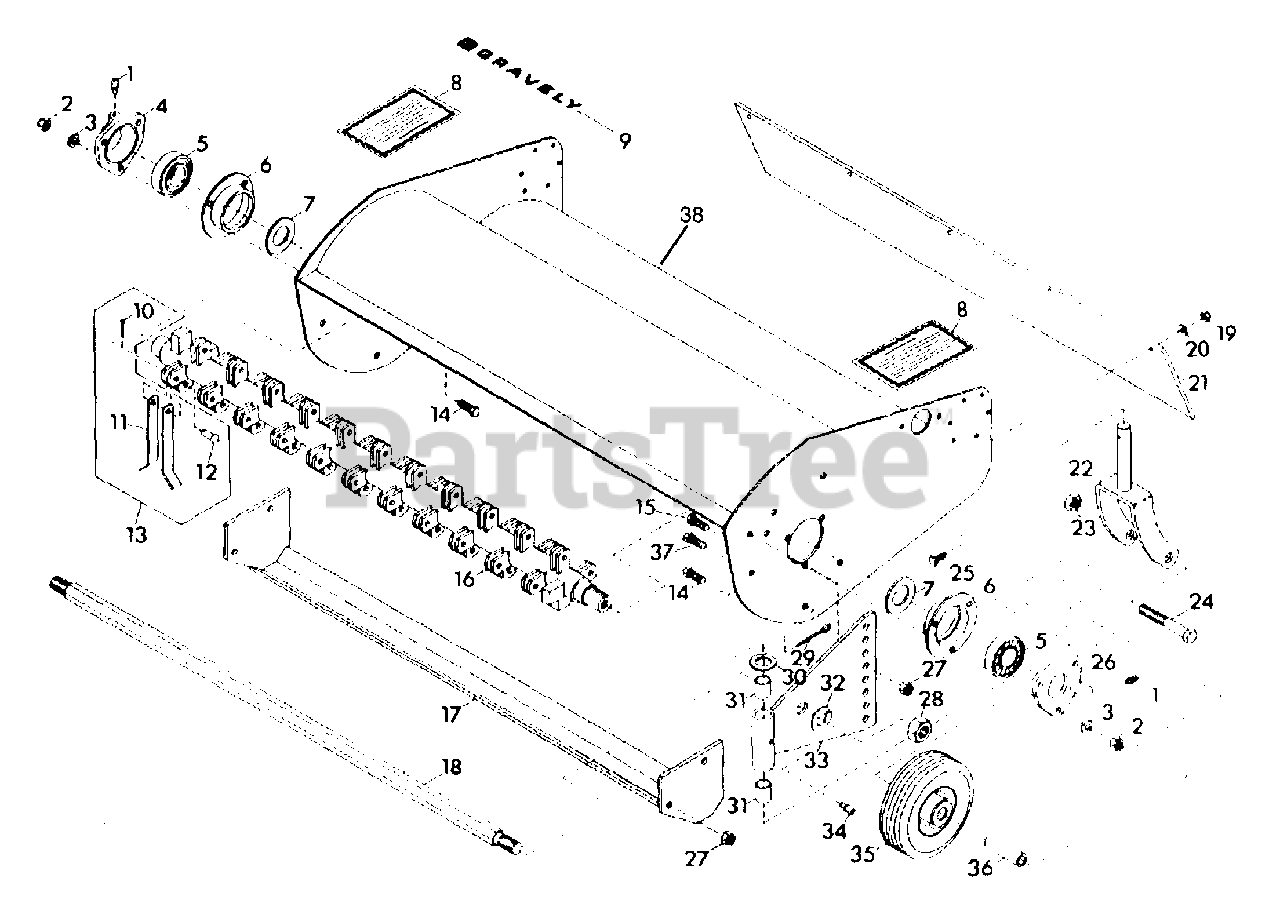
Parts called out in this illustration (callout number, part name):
1	013, Lube
2	Nut-Hex .375-24 Grade 2
3	Washer-Locking .375 x .094
4	Cap, Bearing
5	Bearing, Cutter Shaft
6	Bearing, Cage
7	Washer, Bearing Shield
8	Decal, Danger
9	Decal, Gravely Logo
10	Pin-Cotter .12 x .75
11	Knife
12	Pin, Knife
13	Kit, Knife Replacement
13	Kit, Knife Heavy Duty
14	Bolt, Hex 3/8-24 x 1.00
15	Bolt-Hex .375-16 x 1.00 Grade 5
16	Shaft, Cutter
17	Skid, Weldment
18	Rod
19	Nut-Locking-Nylon .250-20 Grade 2
20	Washer-Flat-Steel .281 x .625 x .065
21	Shield, Rear Deflector
22	Weldment, Caster Fork
23	Nut-Jam .50-13 Grade 2
24	Bolt-Hex .50-13 x 3.75
25	Bolt-Hex .25-20 x .75 Grade 5
26	Retainer, Grease
27	Nut-Locking-Nylon .375-16 Grade 2
28	Nut-Locking-Center .625-11 Grade 2
29	Pin-Cotter .125 x 1.50
30	Washer-Flat .812 x 1.469 x .134
31	Bearing-.752 x .877 x .75
32	Washer-Lock .625
33	Weldment & Bushing Assembly
34	Fitting-Lube .25-28 x .256
35	Wheel-Caster 6 x 2.00
36	Bushing, Sleeve .516 x .745 x 2.59
37	Bolt-Hex .38-16 x 1.25 Grade 5
38	Housing, Flail Mower
